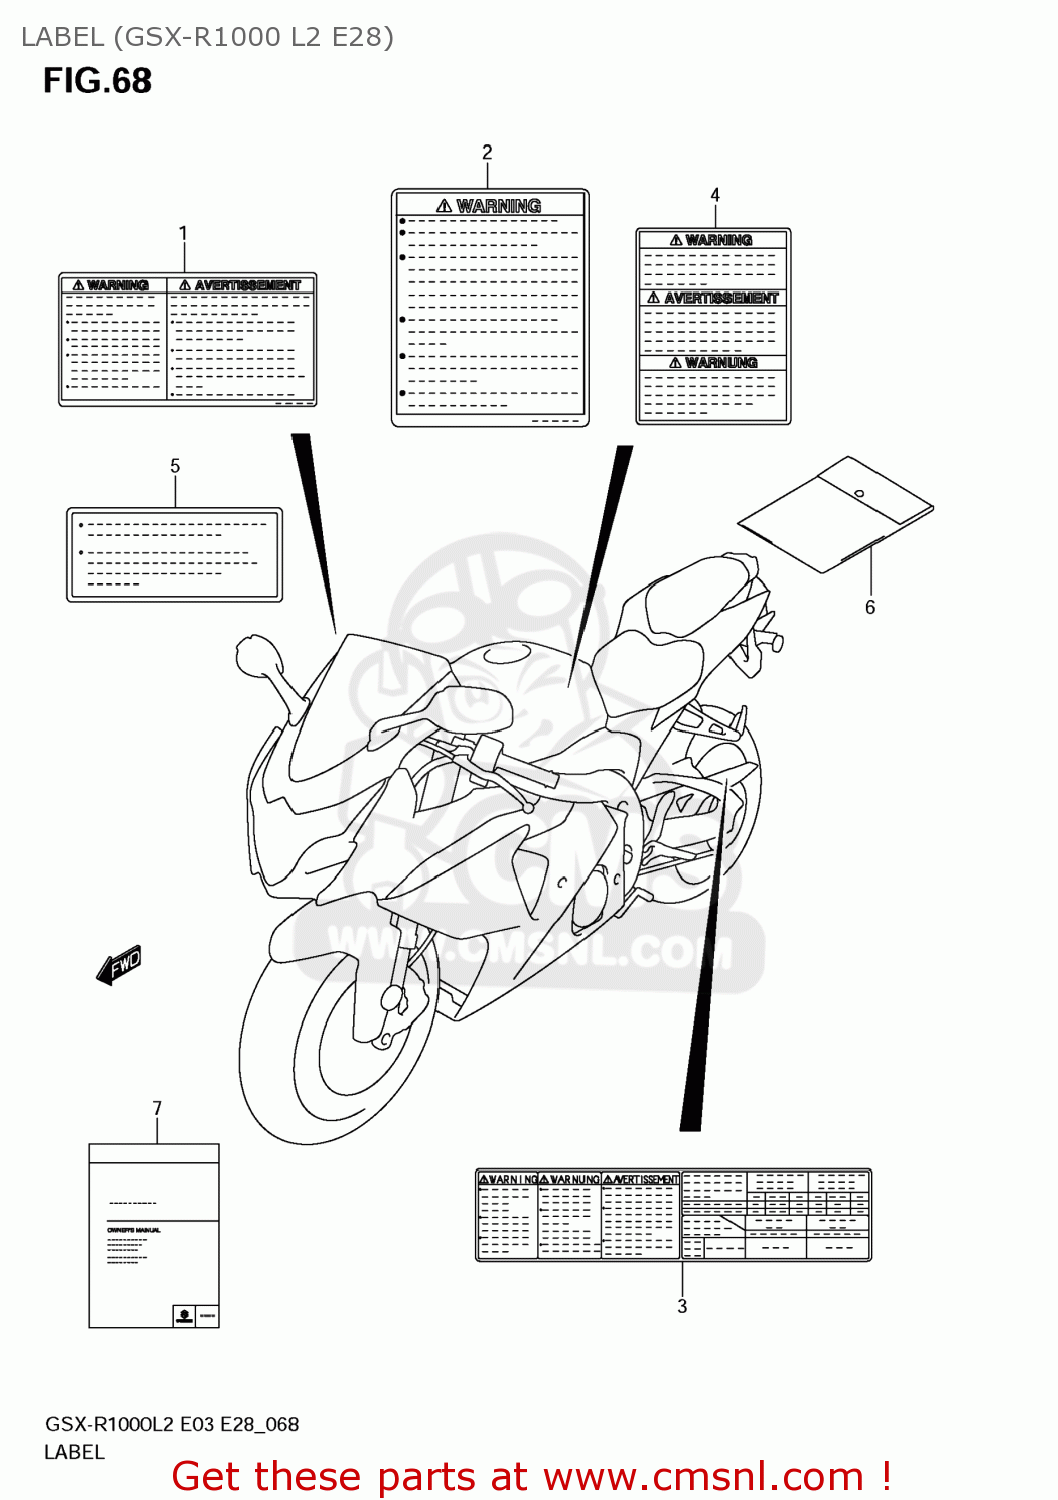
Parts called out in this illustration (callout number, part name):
1	LABEL,GENERAL WARNING
2	LABEL,SCREEN
3	LABEL,TIRE INFORMATION
4	LABEL,WARNING STEERING
5	LABEL,FUEL INFORMATION
6	BAG,OWNER'S MANUAL
7	MANUAL,OWNER'S
